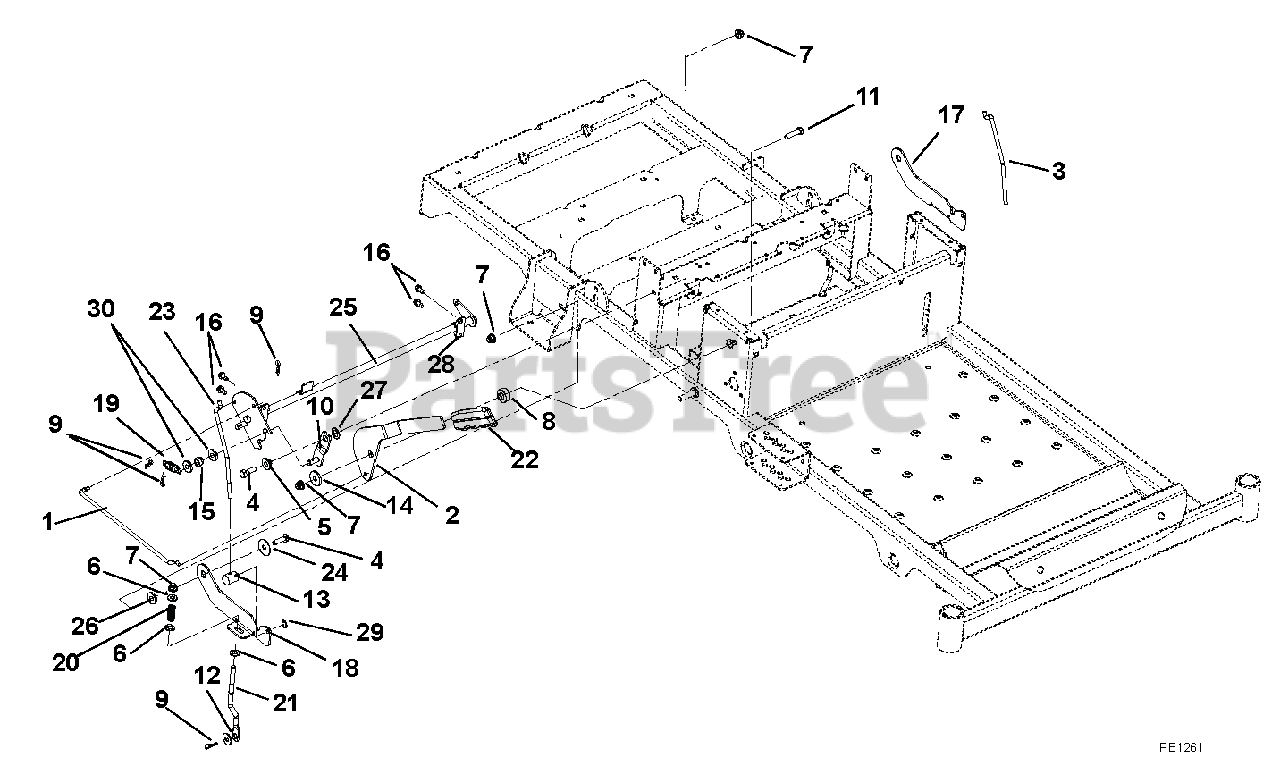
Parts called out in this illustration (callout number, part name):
1	LINK, BRAKE HANDLE
2	HANDLE, PARKING BRAKE
3	LINK, NEUTRAL LH
4	@BLT-HEX .31-18X1.00 GR5 YWZC
5	BSHG-FLG .32X.500X.344X.880
6	@WSHR-FL-STL.344X.688X.065YWZC
7	@NUT-LK-NYL-FLG .31-18 YWZC
8	SPCR,BRAKE .32X.49X.192X1.00
9	PIN-HAIR INT .08X.18X1.18 YWZC
10	WELDMENT,DETENT ARM
11	@BLT-HEX .31-18X1.25 GR5 YWZC
12	@WSHR-FL-STL.38X.875X.083 YWZC
13	TRUNION, 1/4-20
14	WSHR-FL-STL .344X1.125X.135
16	SCR-TAP .25-20X.50 HWH TR YWZ
17	LATCH,LH NETURAL
18	LATCH,RH NETURAL
19	SG-TENS .072X.565X1.87
20	SPRING, COMPRESSION
21	LINK, BRAKE COG
22	GRIP, PARKING BRAKE (YELLOW)
23	LINK, NEUTRAL RH
24	WSHR-FL-STL .347X1.254X.048YWZ
25	WELDMENT, BRAKE SHAFT
26	BSHG, FLG .325X.499X.26X.88
27	WSHR-FL-STL .52X.827X.062 YWZC
28	BUSHING-.50 CLAMP BLOCK MOLDED
29	RG-RTNG-EXT .250X.025
30	WSHR,.385X.745X.030 STL YWZC
